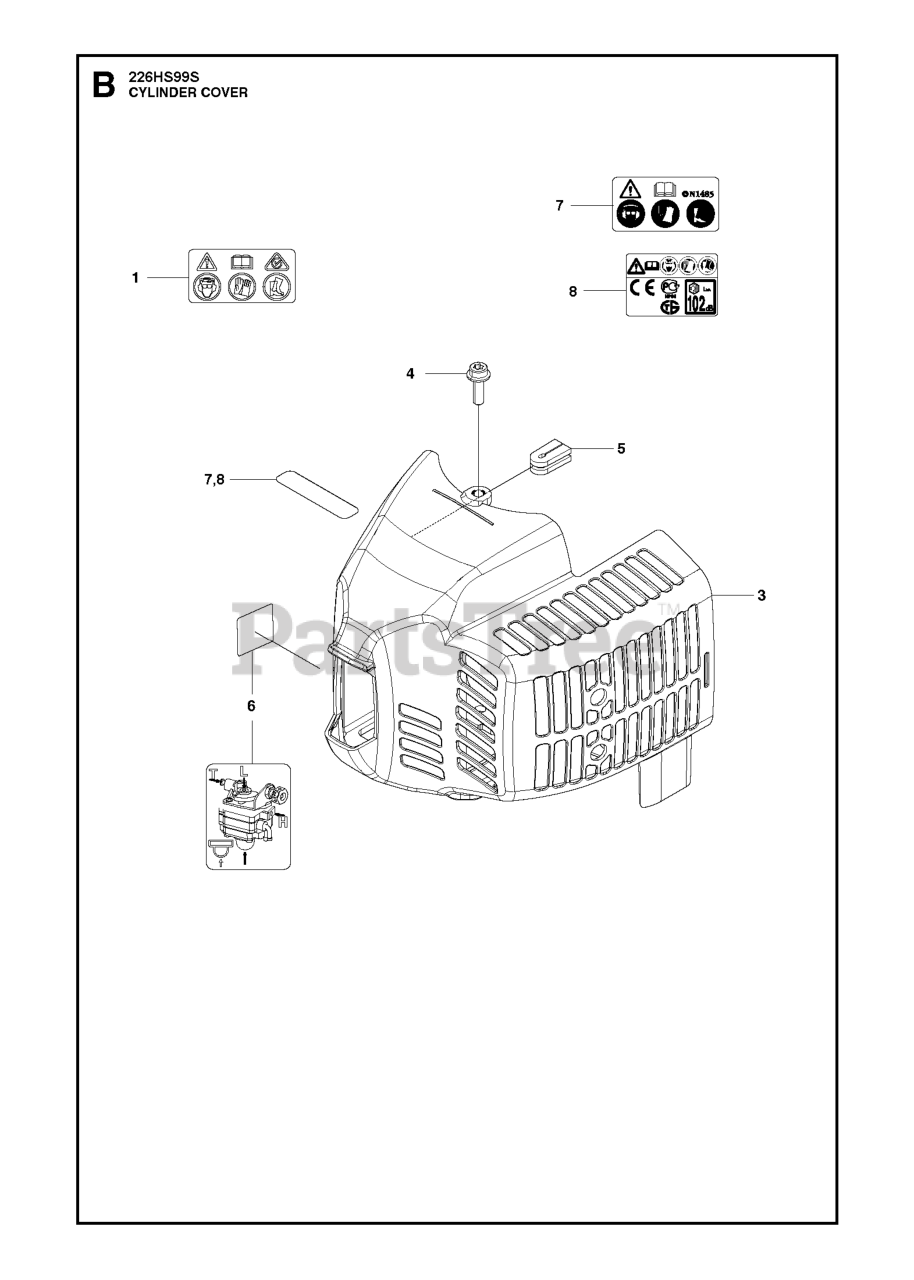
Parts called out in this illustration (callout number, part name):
1	DECAL
3	COVER ENGINE
6	DECAL ADJ LOCATION
7	LABEL WARNING
